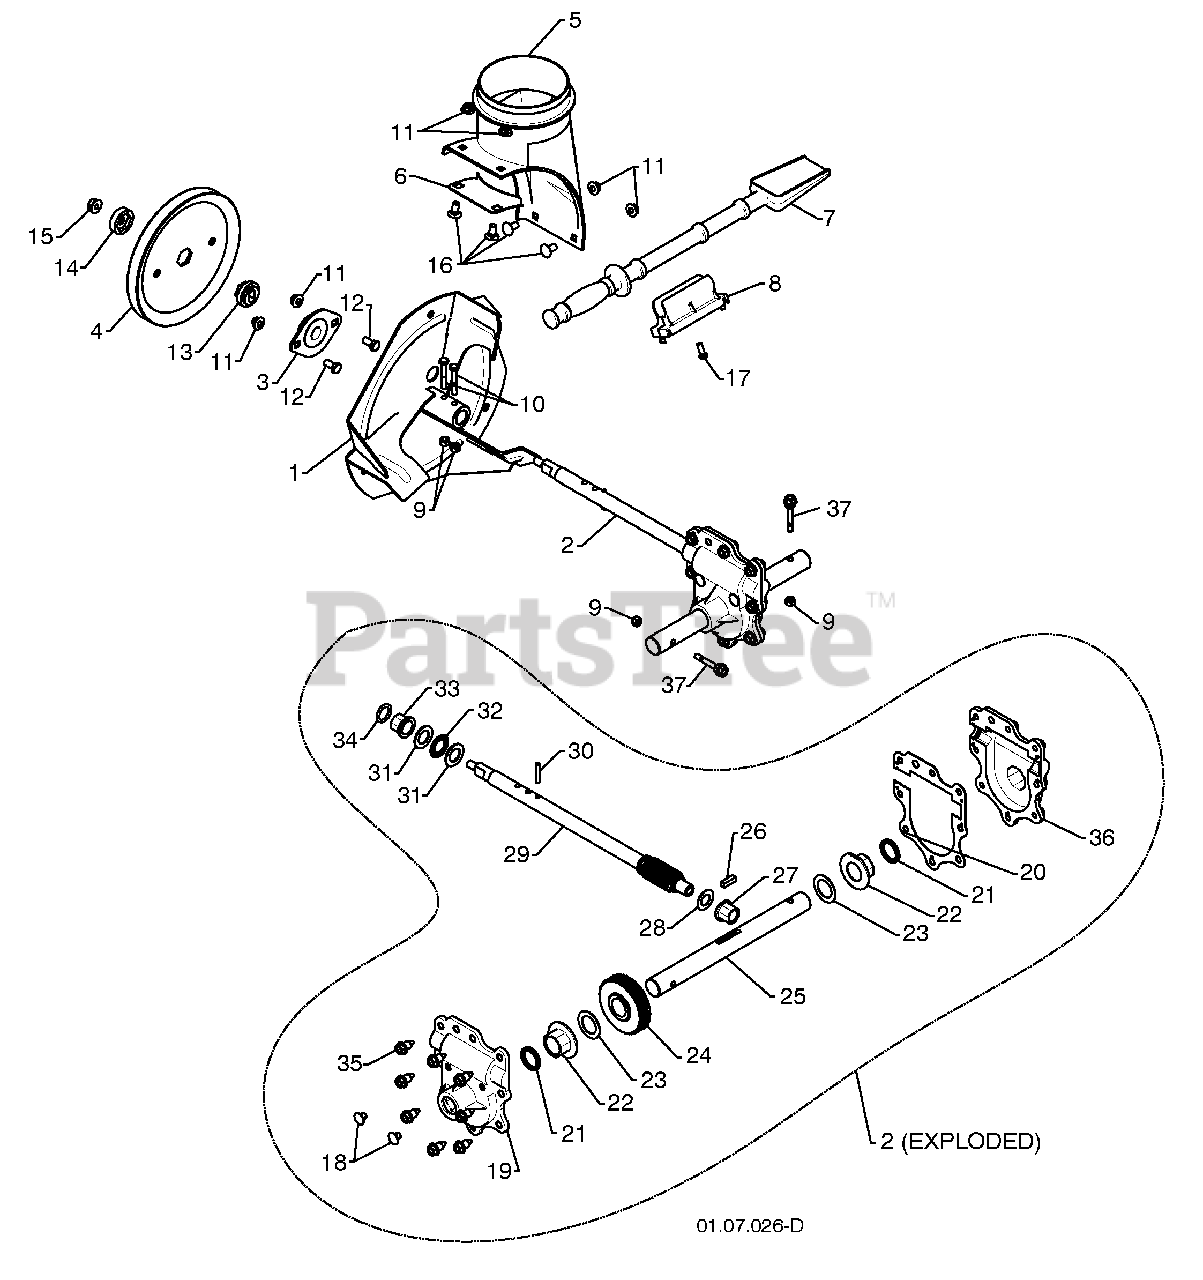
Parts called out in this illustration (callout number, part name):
1	IMPELLER
2	GEARBOX ASSEMBLY
3	BEARING
4	IMPELLER PULLEY
5	DISCHARGE BASE
6	CORNER BRACKET
7	CLEAN OUT TOOL
8	TOOL CLIP
9	NUT 1/4-20
10	SCREW 1/4-20 X .625
11	NUT 5/16-18
12	SCREW 5/16-18 X .625
13	IMPELLER HUB
14	IMPELLER SLEEVE
15	NUT 3/8-16
16	CARRIAGE BOLT
17	SCREW 13-16 X .625
19	GEARBOX COVER RH
20	GASKET
22	BEARING
23	THRUST WASHER 1.00
25	AUGER SHAFT
26	SQUARE KEY
28	THRUST WASHER
29	IMPELLER SHAFT
31	THRUST WASHER
32	THRUST BEARING
34	O-RING
35	SCREW 5/16-18 X .750
36	GEARBOX COVER LH
37	SHEAR BOLT
